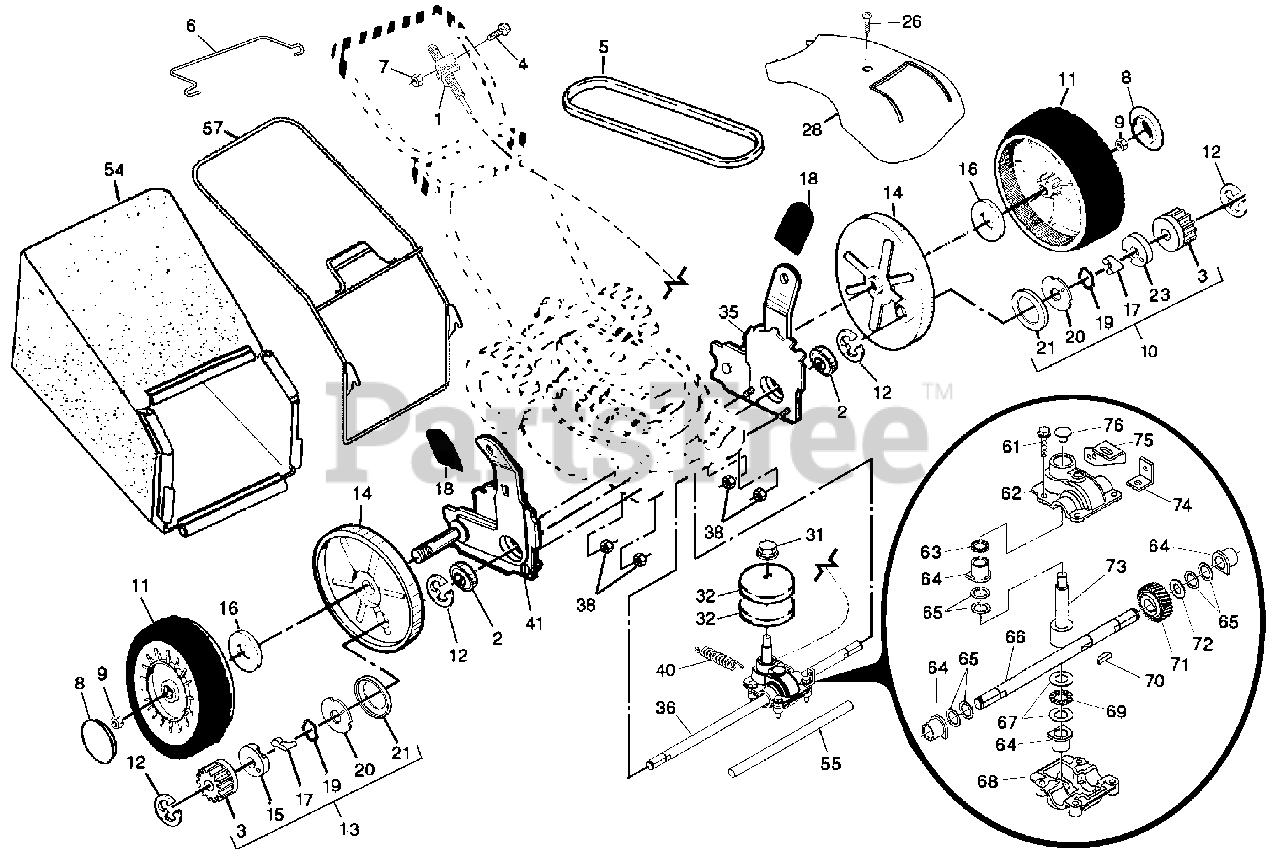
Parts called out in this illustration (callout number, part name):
1	Vari-Speed Drive Control Assembly
2	Bearing, Wheel Adjuster
3	Gear, Pinion
6	Bar, Control, Drive
7	Nut, Hex
8	Hubcap
9	Locknut
10	Pinion Assembly, LH
11	Wheel & Tire Assembly
13	Pinion Assembly, RH
14	Dust Cover
15	Retainer, Drive. RH
16	Washer 1/2 x 1-1/2 x .134
18	Selector Knob
19	Spring, Torsion
20	Disc, Drive
21	Seal, Pinion
23	Retainer, Drive, LH
26	Pan Head Tapping Screw #10-24 x 2-3/4
28	Drive Cover
31	Hex Flange Nut
32	Pulley Half, Drive
35	Kit, Wheel Adjuster, LH
36	Gear Case Assembly, Complete
38	Locknut 1/4-20
40	Spring
41	Kit, Wheel Adjuster, RH
54	Grassbag Assembly
55	Driveshaft Cover
61	Screw, Tapping 1/4-20 x .62
62	Gear Case, Upper, FWSS
66	Drive Shaft, 21" FWGD
67	Washer, Thrust
68	Gear Case, Lower, FWSS
69	Bearing, Needle, Thrust
70	Key, Hi-pro
71	Gear, Helical
73	Shaft, Worm
74	Return Arm
75	Bracket, Transmission
